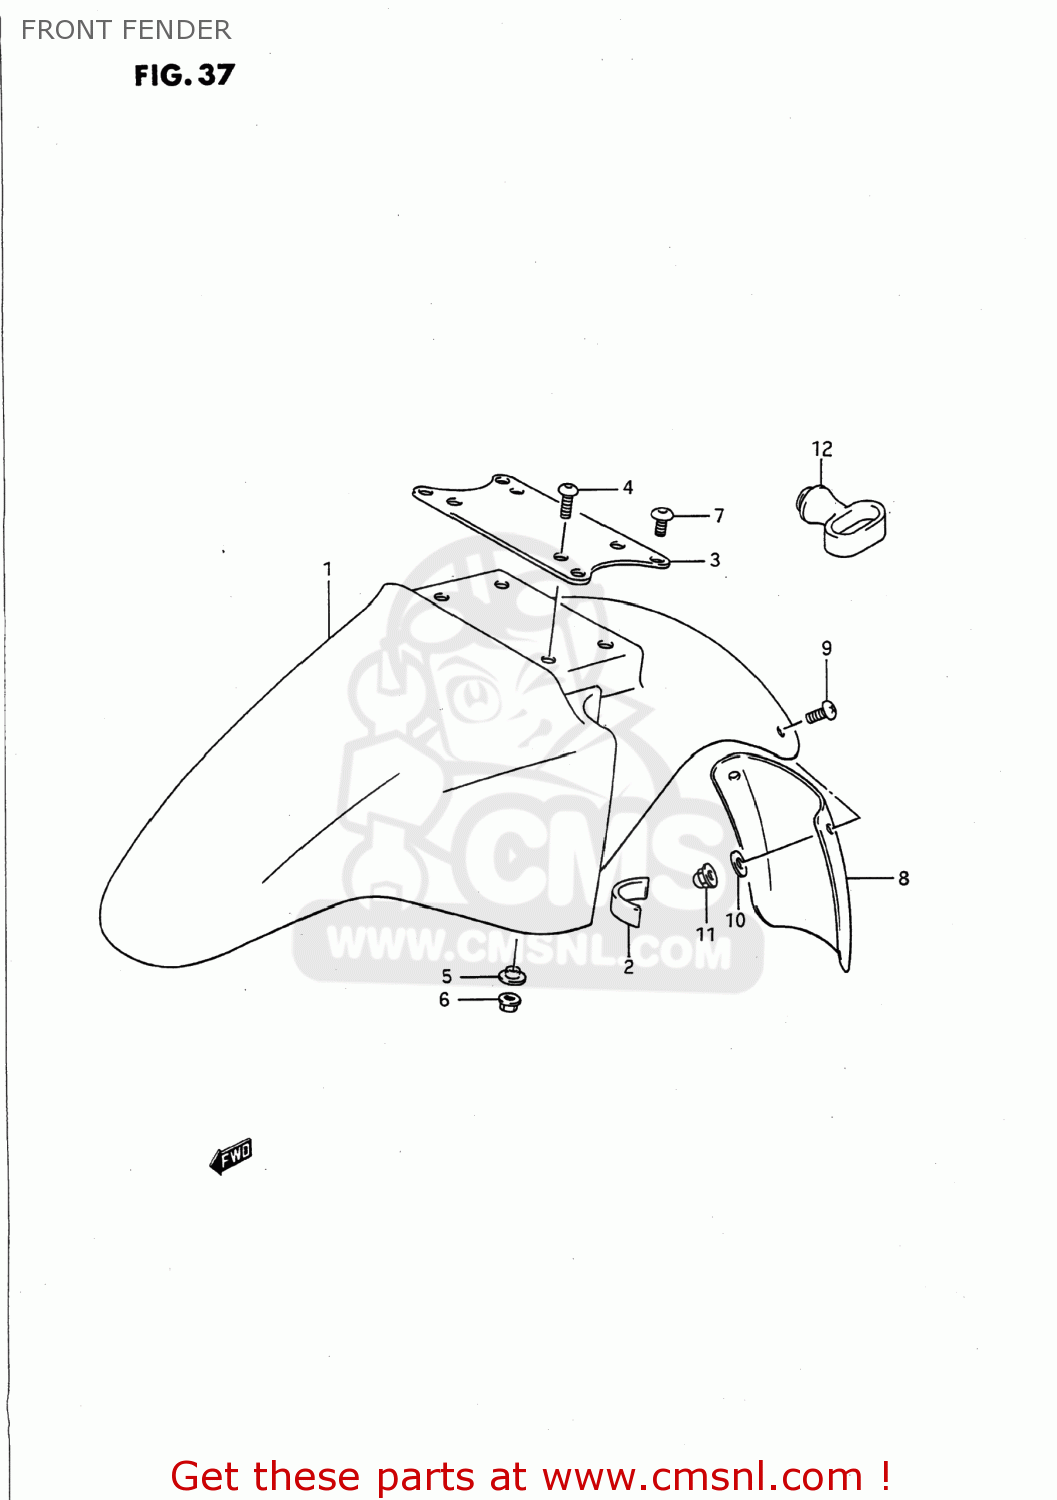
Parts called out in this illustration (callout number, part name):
1	FENDER,FRONT
2	CUSHION,FRONT FENDER
3	BRACE,FR FENDER
4	SCREW(5X16)
5	WASHER
6	NUT
7	SCREW(6X12)
8	MUDGUARD,FR FENDER
9	SCREW
10	WASHER(5.5X20X1.2)
11	NUT
12	GUIDE,CABLE
